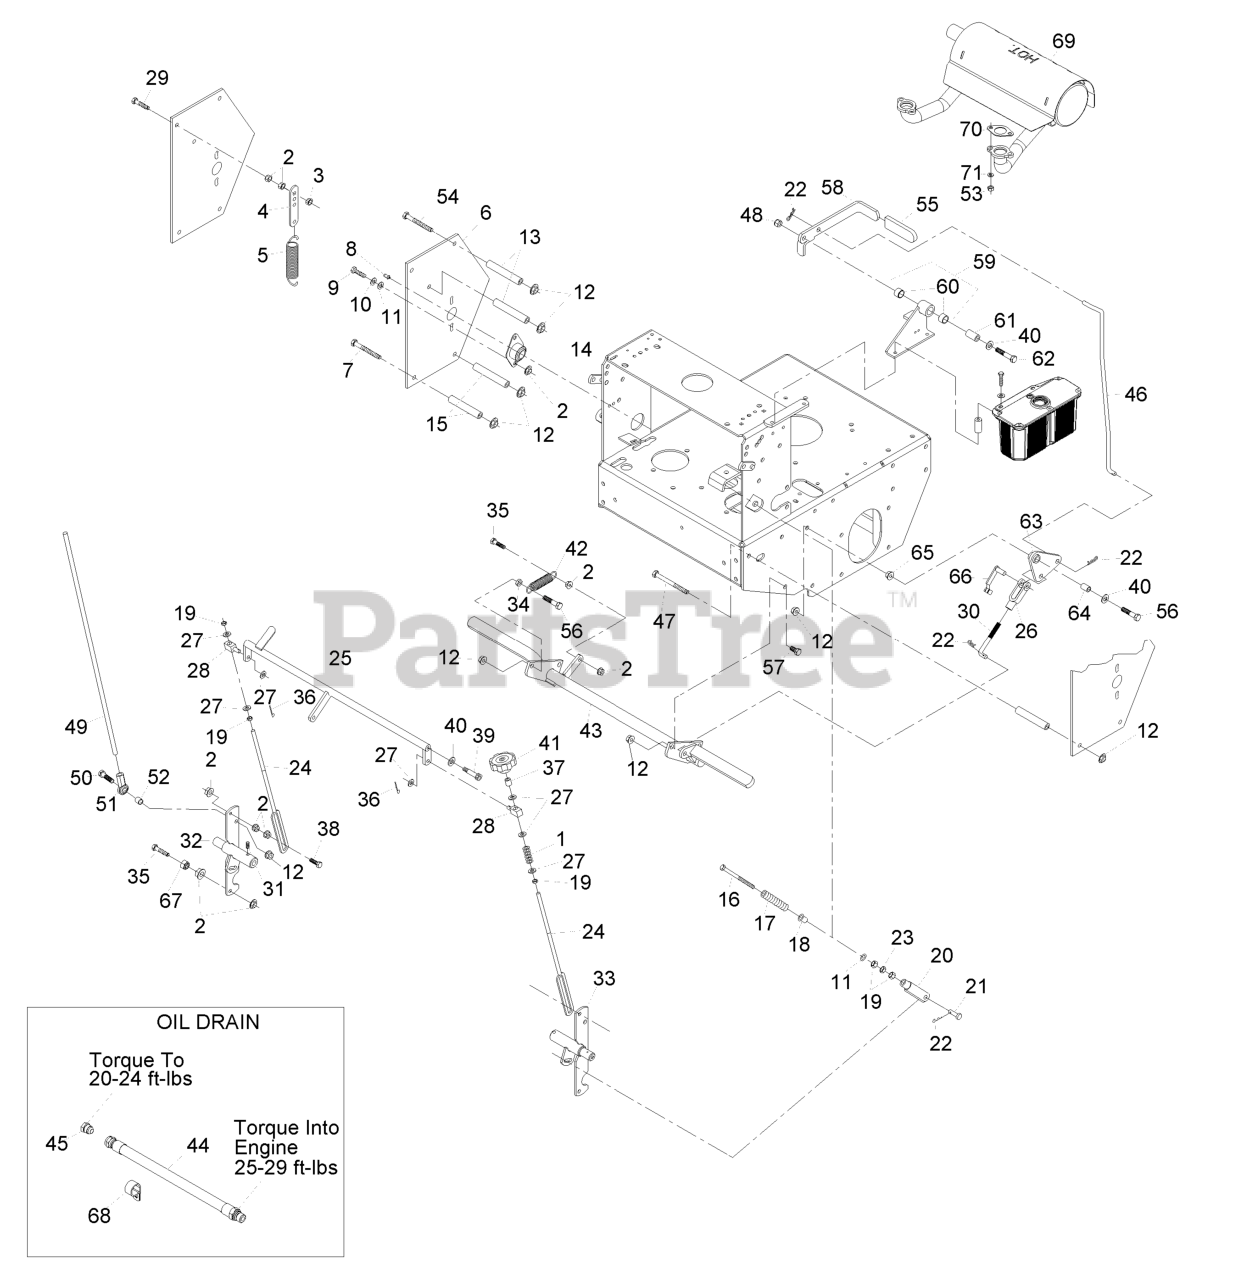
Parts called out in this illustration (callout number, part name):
1	SPRING-COMPRESSION
3	NUT-LOCK, NI
4	TAB-SPRING, EXTENSION
5	SPRING-EXTENSION
6	SHIELD-CONTROL
7	SCREW-HH
8	FITTING-GREASE
9	SCREW-HH
10	WASHER-LOCK
11	WASHER-FLAT
12	NUT-HHF, WHIZ
13	SPACER-SHIELD
14	BEARING-FLANGE, SIDE
15	SPACER-SHIELD
16	BOLT-RETURN, NEUTRAL
17	SPRING,COMPRESSION (NEUT)
18	BUSHING-FLANGED
19	NUT-HEX
20	YOKE-ADJUSTABLE
21	PIN-CLEVIS
22	PIN-COTTER
23	NUT-JAM
24	LINK-CONTROL, SPEED
25	CRANK-CONTROL, SPEED
26	YOKE-LINKAGE, BRAKE
27	WASHER-PLAIN
29	BOLT-TAP, HH
30	LINKAGE-LOWER
31	SCREW-SET
32	SHAFT-CONTROL, LH
33	SHAFT-CONTROL, RH
34	NUT-JAM
35	SCREW-HH, SPECIAL
36	PIN-COTTER
38	SCREW-HH
39	SCREW-HSH
40	WASHER-FLAT
41	KNOB-TRACKING
42	SPRING-IDLER
46	LINKAGE,UPPER- TTHP
47	SCREW-HH
48	NUT-LOCK, NI
49	LINK,DRIVE (PLTD)
50	SCREW-HH
51	JOINT-BALL END, LH
52	SPACER-TUBE, PUMP LINK
54	SCREW-HH
55	GRIP-LEVER
56	SCREW-HH
57	SCREW-HH
58	LEVER,PARK BRK W/DECAL
59	BRACKET ASM
60	SLEEVE-BUSHING
61	BUSHING-PIVOT
62	SCREW-HH
63	BELLCRANK ASM
64	BUSHING-PLASTIC
66	PIN-SPRING, CLEVIS
67	NUT-JAM
68	CLIP-LOOM
69	MUFFLER,HORIZONTAL
70	GASKET-EXHAUST
71	WASHER-LOCK
